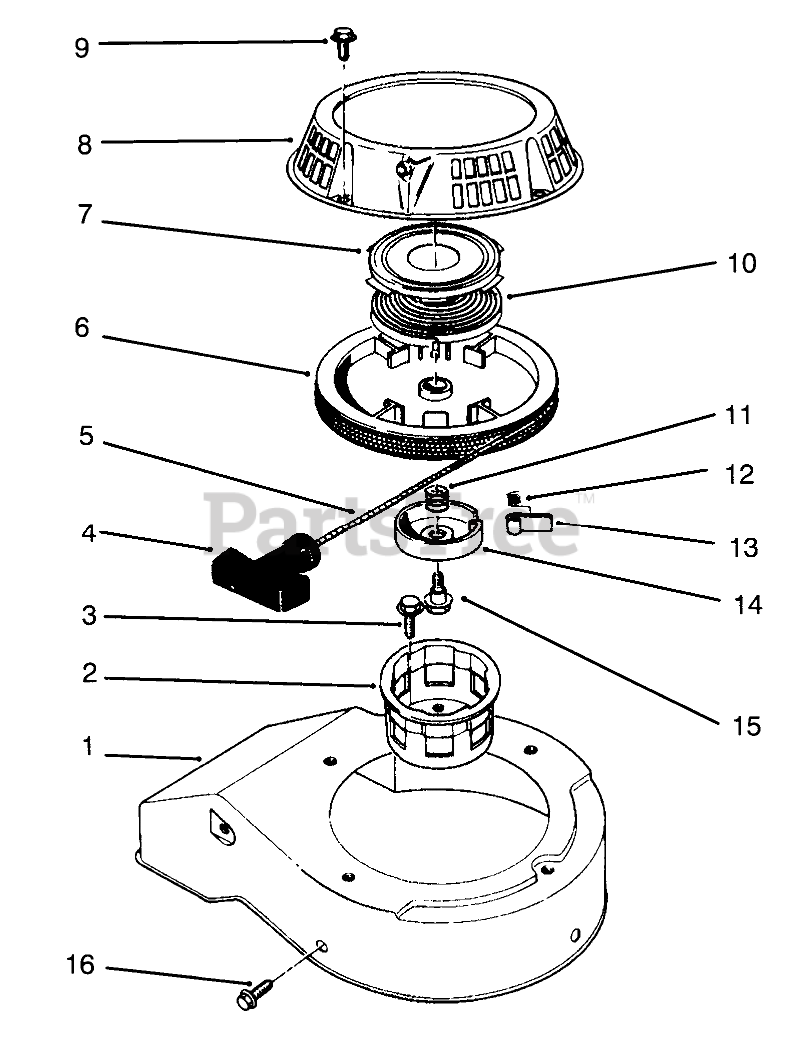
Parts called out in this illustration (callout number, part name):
1	Cover-Cooling Fan
2	PULLEY-CUP, STARTER
4	HANDLE-RECOIL
5	ROPE-STARTER
7	Retainer-Spring, Recoil
8	CASE-STARTER
9	SCREW-HHF
10	Spring-Recoil
11	SPRING
12	SPRING
14	RETAINER
